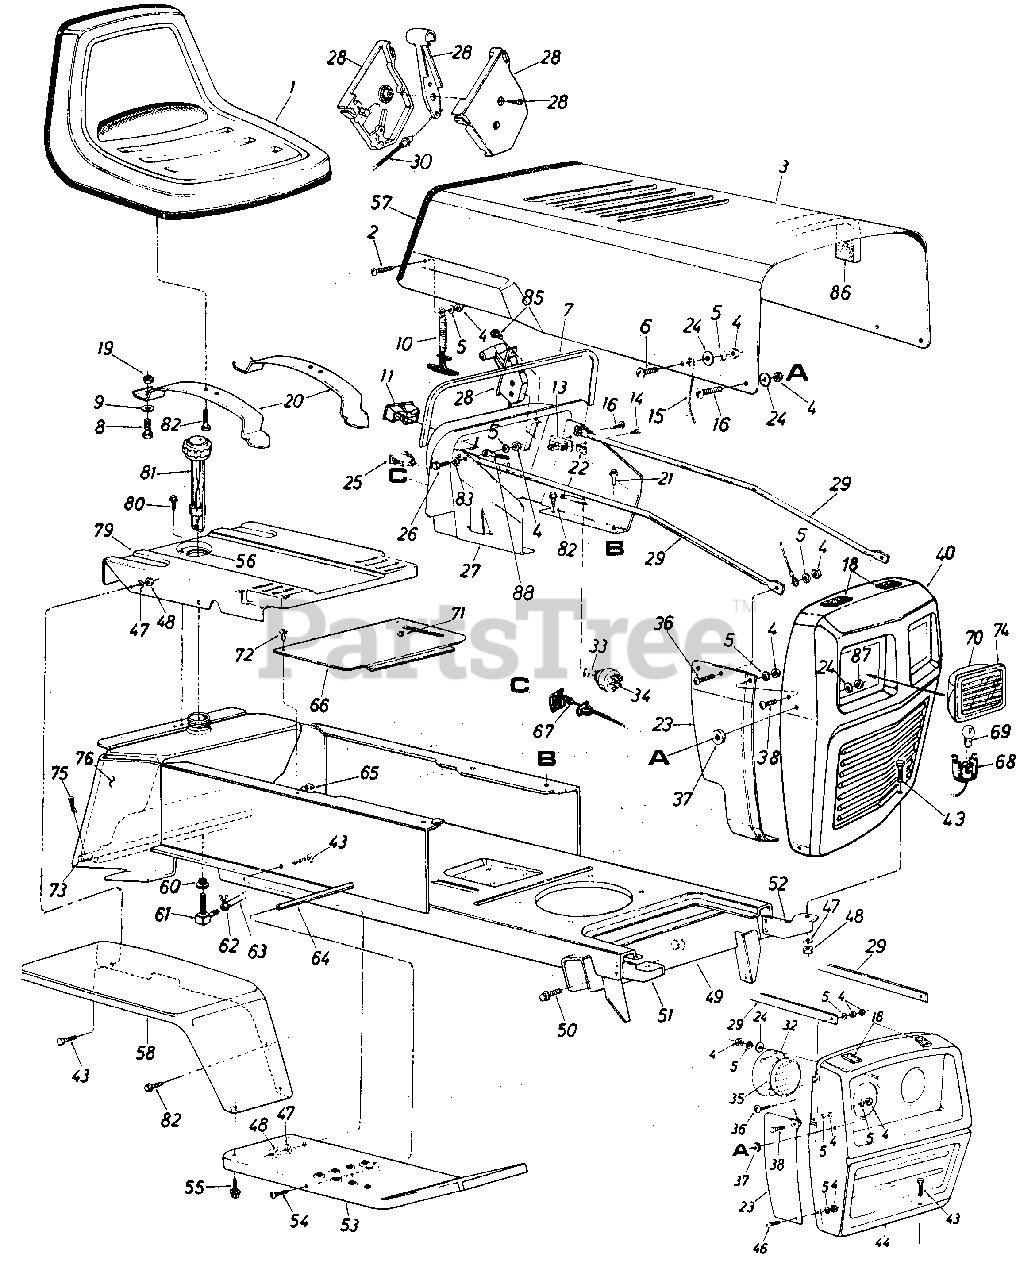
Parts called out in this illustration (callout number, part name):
1	Seat Assembly
2	Truss Mach. Scr. 1/4-20 x .50" Lg.
5	L-Wash. 1/4" I.D.
6	Truss Mach. Scr. 1/4-20 x .50" Lg.
7	Vinyl Molding Strip-29"
8	Hex Nylon Scr. 1/2-13 x .75" Lg.
9	Fl-Wash 50" I.D. x 1.00" O.D. x .090
10	Hood Latch Ass'y.
11	Ammeter
13	Circuit Breaker 8 Amp.
14	Hex Tap Scr. #10 x .50"
15	Hood Stop
16	Truss Mach. Scr. 1/4-20 x .75" Lg.*
18	PVC Foam Strip 1/2 x 1.OO" x 2.00" Lg.
19	Hex Nut 1/2-13 Thd.
22	Speed Nut #10Z
23	Grille Side Panel-R.H.
24	Fl-Wash. 1/4" I.D.
25	Light Switch
26	Truss Hd. Scr. 1/4-20 x 1.00" Lg.*
27	Dash Panel Ass'y.
28	Throttle Control Box Comp.
29	Grille Positioning Rod
30	Throttle Control Cable
32	Head Lamp Retainer
33	Ignition Key
34	Ignition Switch
35	Head Lamp
36	Truss Machine Scr. 1/4-20 x .75" Lg.
37	Rubber Washer
38	Truss Mach. Scr. 1/4-20 x .50" Lg.
44	Grille (Painted)
46	Truss Mach. Scr. 1/4-20 x .50" Lg.
47	L-Wash. 5/16" I.D.
48	Hex Nut 5/16-18 Thd.
49	Lower Frame Ass'y.
50	Hex Thd. Rolling Scr. 5/16" x.75" Lg.
51	Grille Mount Brkt.-R.H.
52	Grille Mount Brkt.-L.H.
53	Running Board-R.H.
54	Truss Mach. Scr. 5/16-18 x .75" Lg.
55	Hex Thd. Rolling Scr. 5/16-24 x .75" Lg.
56	Grommet
57	Vinyl Moulding Strip-30"
58	Fender Ass'y.-R.H.
60	Bushing
61	90ø Nipple
62	Hose Clamp 3/8"
63	Gas Line 46" Lg.
64	Running Board Rod
65	Speed Nut #10-24
66	Transmission Cover Ass'y.
67	Choke Control Comp.
68	Socket
69	Lamp
70	Headlight Housing
71	Snap Bushing
72	Truss Hd. Scr. #10 x .50"
73	Hitch Rod
74	Lenst
75	Internal Cotter Pin
76	Gas Tank
79	Seat Plate
80	Hex Thd. Rolling Scr. 5/16-24 x .75" Lg.
81	Gas Gauge
82	Hex Thd. Rolling Scr. 5/16-24 x .75" Lg.
83	External Wash. 1/4" I.D.
85	Truss Mach. AB-Tap Scr. #10 x .50" Lg.
86	PVC Foam Strip
87	Hex L-Nut 1/4-20 Thd.
88	Ground Wire
